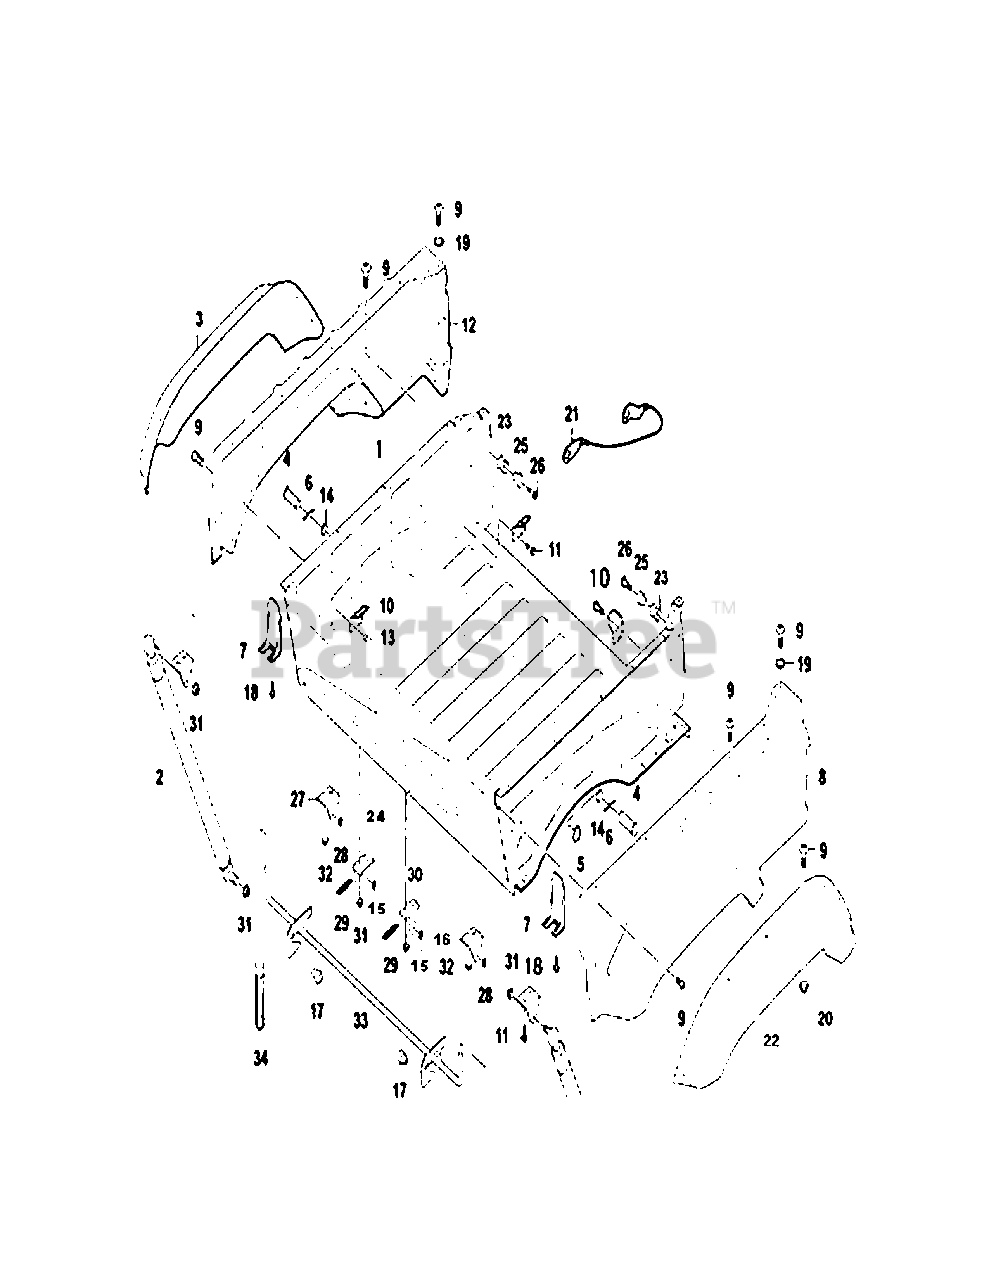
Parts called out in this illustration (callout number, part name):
1	Rear Carrier Assy
2	Gas Spring Assy
3	Rear cargo fender (right)
4	Pin 12×62
5	Rubber Cushion III
7	Invert Bracket Board, Carrier
8	Left Side Board Assy, Carrier Yellow
8	Left Side Board Assy, Carrier Camo
9	Cross large plate head screw M6×16
10	Drawstring Pothook
11	Hexagon Flange Bolt M6×12
12	Right Side Board Assy, Carrier Yellow
12	Right Side Board Assy, Carrier Camo
13	Cap Nut M6×17
14	Wahser13×24×1.5
15	I-Shaped Rubber Ring IV
16	retroflexion support bracket
17	Nylon Bushing IV
19	Washer6×18×1.6
20	Hexagon Flange Self-Lock Nuts M6
21	Trunk Cable
22	Rear cargo fender (left)
23	I-Shaped Rubber Ring
24	Right Mounting Plate, Invert Bracket Assy
25	Bushing 6.5×9×22×17
26	Hexagon flange bolt M6×30
27	Left Invert Bracket Support Lug
28	I-Shaped Rubber Ring IV
29	Tension Spring III
30	Left Mounting Board, Invert Bracket
31	Hexagon Flange Lock Nut M8 (Metallic Insert)
32	Hexagon Flange Nut M6
33	Invert Bracket Assy, Carrier
34	Handle Sheath II
35	Gas Spring Mounting Plate
36	Gas Spring Assy
37	Cargo Bed Right Decoration Plate
38	Right Mounting Plate, Invert Bracket Assy
